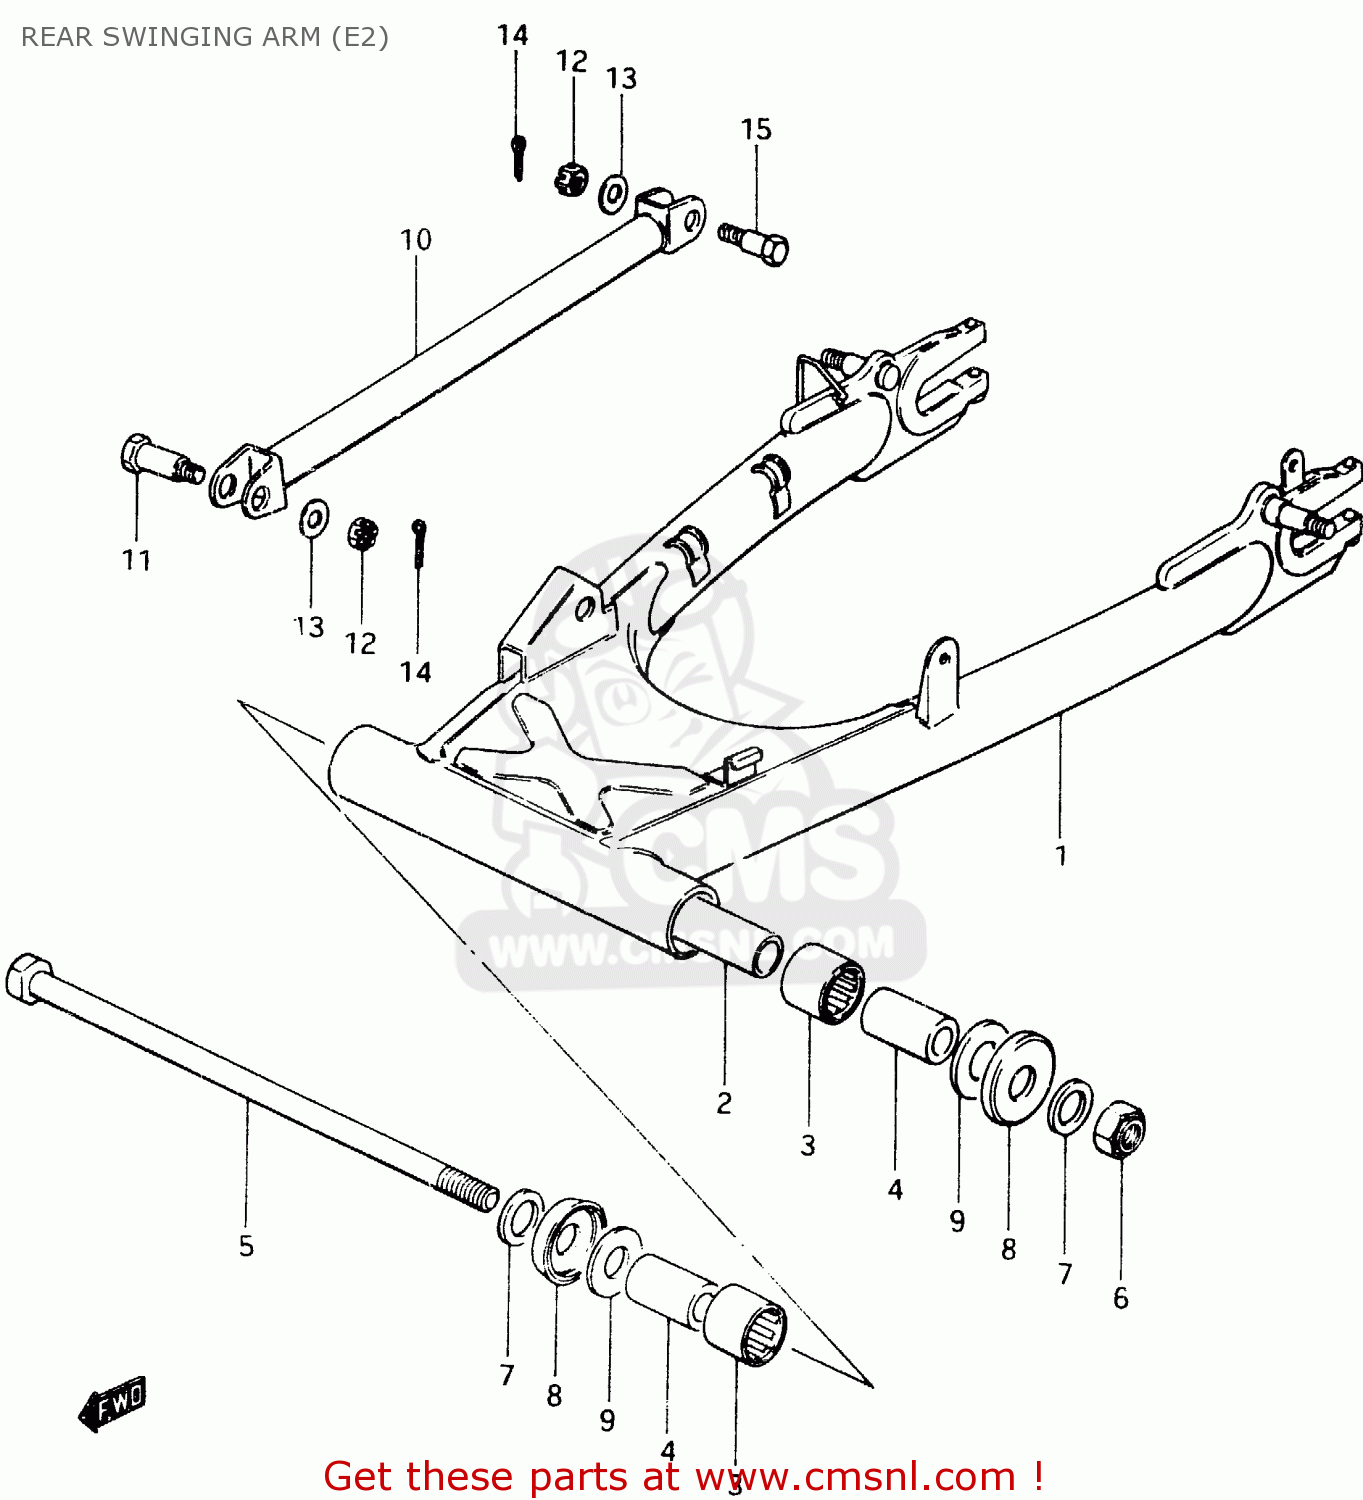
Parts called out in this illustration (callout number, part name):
1	REAR SWINGING ARM
2	SPACER,RR SWGARM PIVOT CTR
3	BEARING(22X29X30)
4	SPACER,RR SWGARM PIVOT
5	SHAFT,REAR SWING ARM
6	NUT 14MM
7	WASHER
8	CVR,RR SWGARM DUST SEAL(OD:40)
9	WASHER(14.2X34X1)
10	TORQUE LINK, REAR
11	BOLT
12	NUT
13	WASHER
14	PIN 20X20
15	BOLT(10X39)
